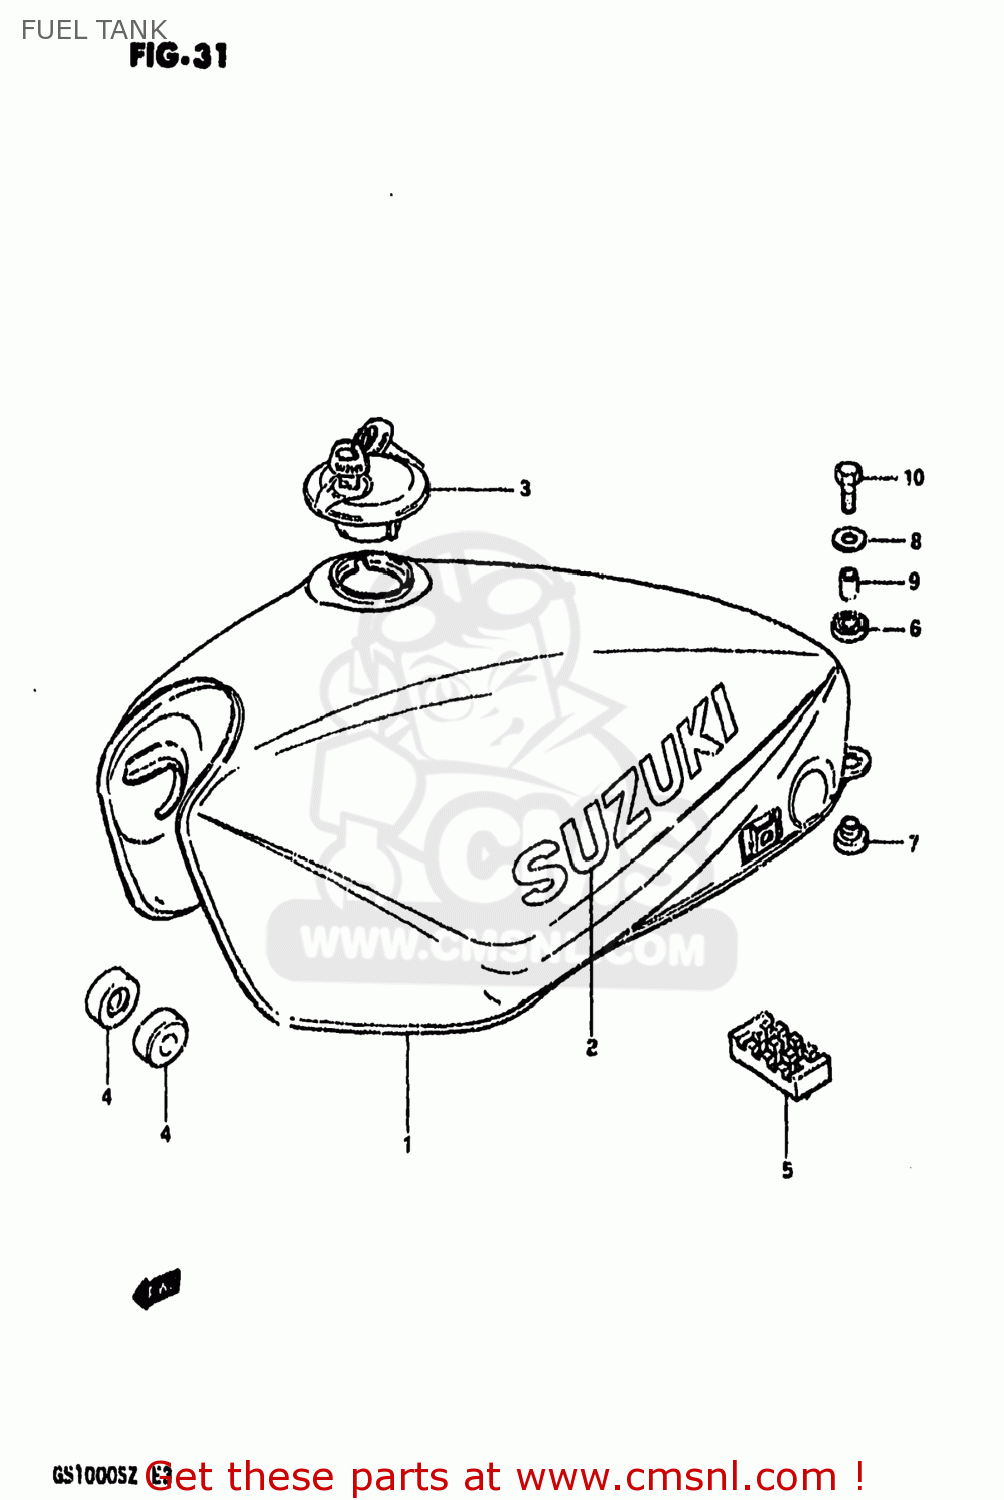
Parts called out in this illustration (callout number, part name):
1	TANK, FUEL (SILVER)
2	EMBLEM(ORANGE)
3	CAP SET,FUEL TANK
4	CUSHION
5	CUSHION,FUEL TANK CTR
6	CUSHION
7	CUSHION
8	WASHER (6.5X24X1.6)
9	SPACER
10	BOLT
